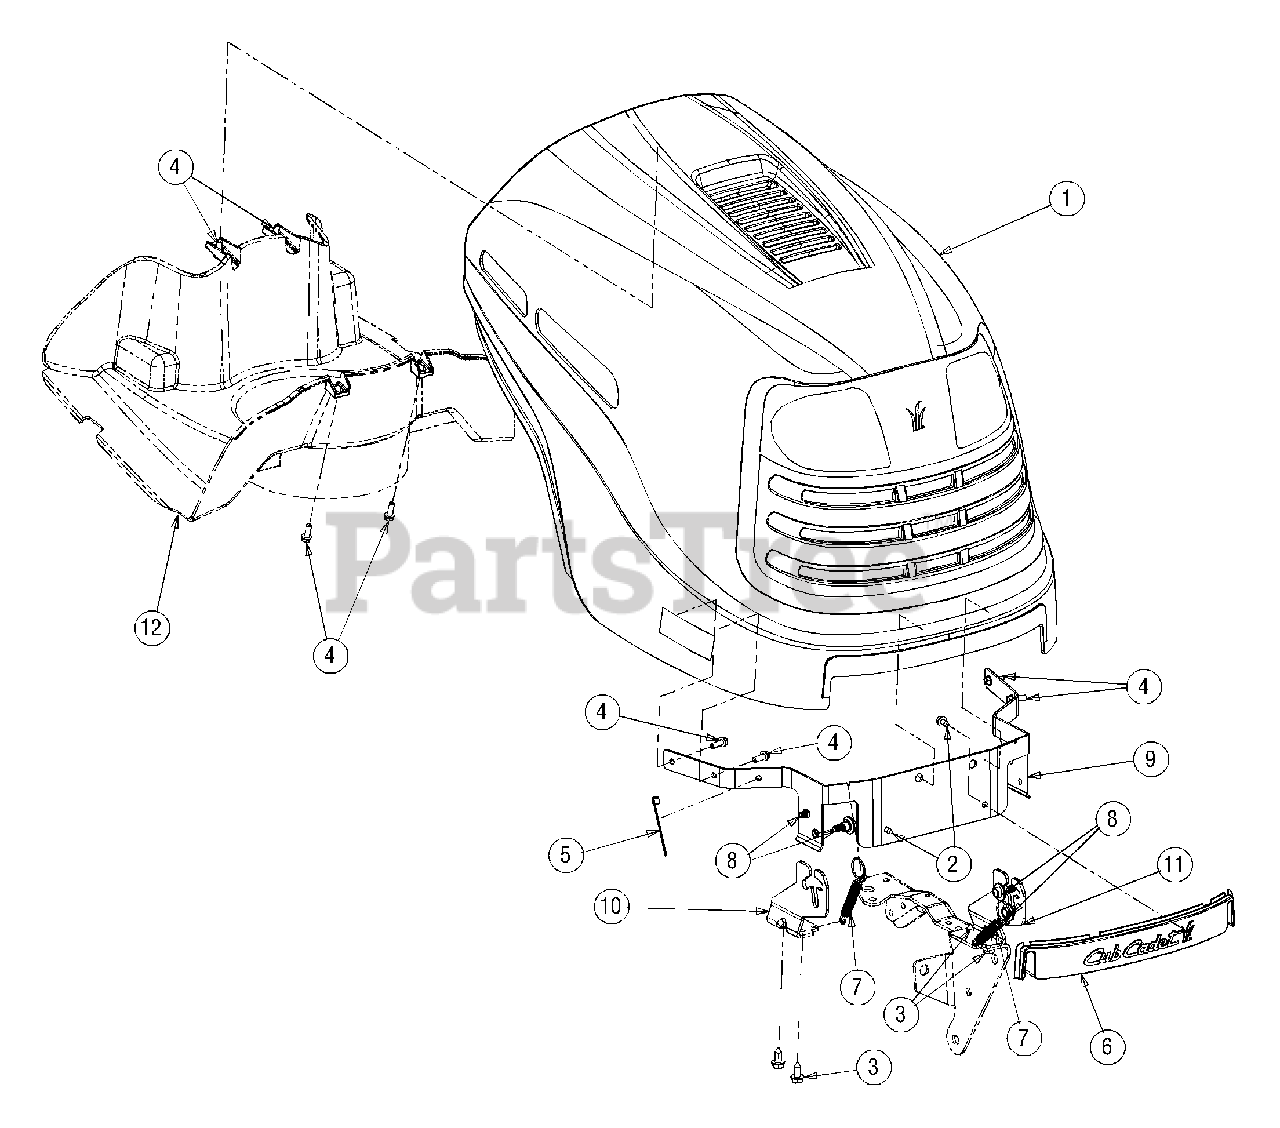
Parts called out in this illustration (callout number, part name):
1	Hood Asssembly:
1	Headlight Harness
1	Minirature Lamp, 12 V
1	Lamp Socket
1	Hood
1	Headlight Lens
1	Headlight Lens Reflector, LH
1	Headlight Lens Reflector, RH
2	Screw, Hex Wash, Hd,Tapp 1/4-20 x .5
3	Self-tapping Screw, 5/16-18 x.625
4	Screw, 1/4-15 x .75
5	Cable Tie
6	Cover, Front Hood
7	Spring, .46 x 4.12
8	Shoulder Screw, .43 x .29 x 5/16-18
12	Hood Plenum (LT1046 & LT1050)
